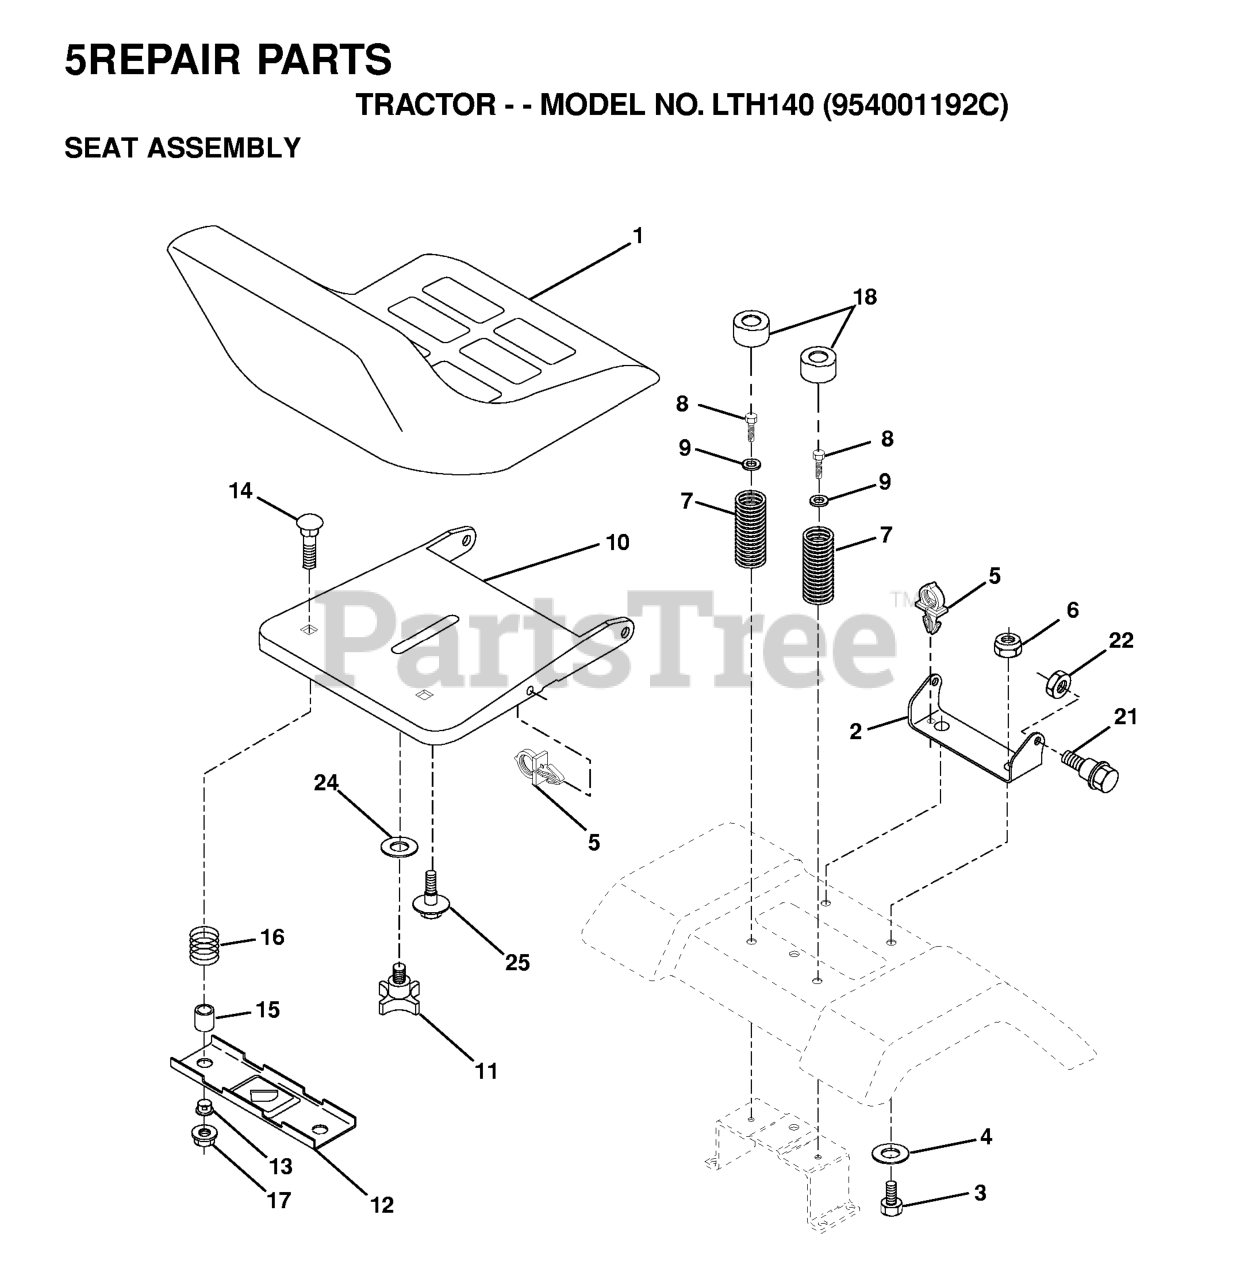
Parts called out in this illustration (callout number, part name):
1	SEAT
2	SEAT PIVOT BRKT
3	BOLT
6	NUT
7	SPRING COMPRESSION
8	SCREW GTV
9	WASHER
10	SEAT PAN
11	KNOB 1/2" YT
12	BRKT SWITCH
14	Bolt Rdhd. Sht. Nk 1/4-20 x 1-3/8
15	SPACER SPLIT 28X.96
17	NUT T
18	CAP SPRING
21	BOLT.SHOULDER.5/16-18
22	NUT.71038.31-18.HEX.NYLOCK
25	BOLT,SHOULD
